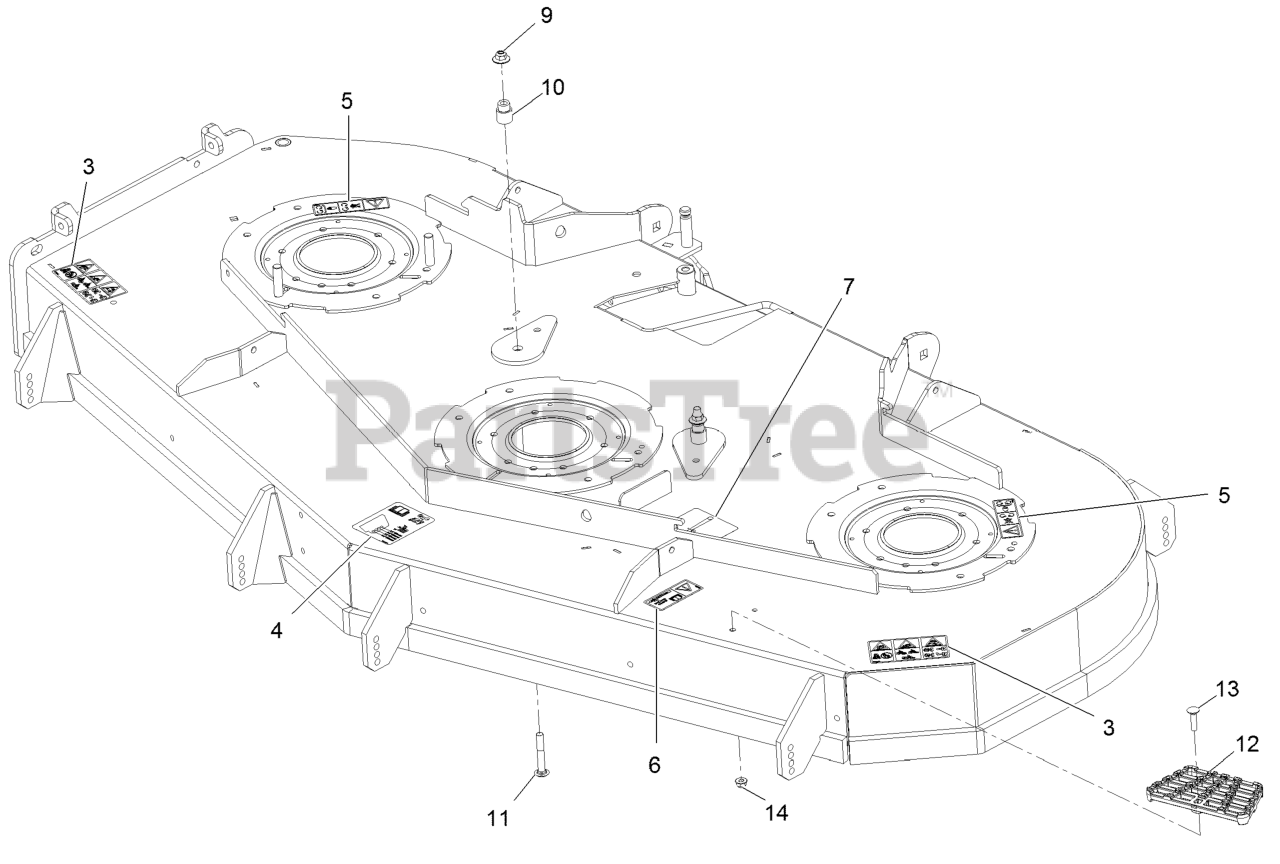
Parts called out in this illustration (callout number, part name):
3	DECAL-DANGER THROWN OBJECTS
4	DECAL-ROLLER, ANTI-SCALP
5	DECAL-COVER, MISSING
6	DECAL-BOLT TORQUE
7	DECAL-BELT ROUTING
9	Nut-Nyloc 3/8-16 Flg
10	BUSHING-IDLER
11	SCREW-CARR
12	STEP-DECK
13	Bolt-Carriage 5/16-18 X 1 1/4
14	NUT-HF, NI
